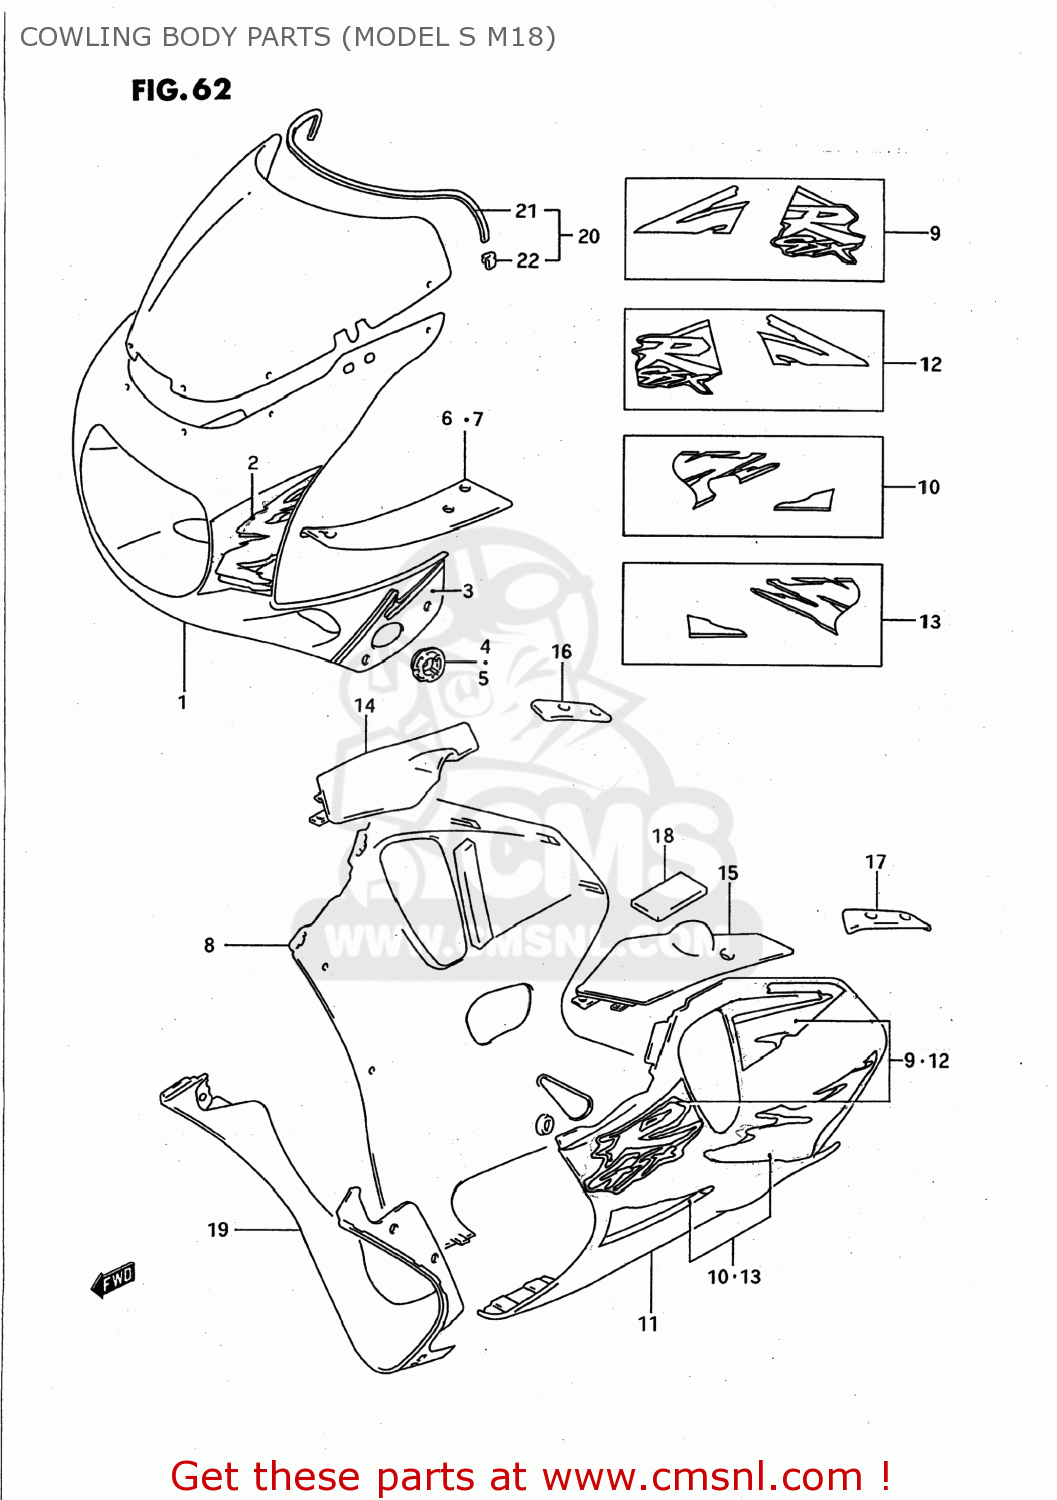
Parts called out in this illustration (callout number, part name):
1	COWLING ASSEMBLY,BODY
2	TAPE SET,COWL BODY FR
3	TAPE SET,COWLING BODY
4	PLATE,TURN SIGNAL,RIGHT
5	PLATE,TURN SIGNAL,LEFT
6	PANEL,COWLING,UPPER,RIGHT
7	PANEL,UPPER,LEFT
8	COWLING ASSEMBLY,UNDER,RIGHT
9	TAPE SET,COWLING,UNDER
10	TAPE SET,COWL UNDER LWR,R
11	COWLING ASSEMBLY,UNDER,LEFT
12	TAPE SET,COWL UNDER,L
13	TAPE,SAET COWL UNDER LWR,L
14	PANEL,LWR FR,R
15	PANEL,LWR FR,L
16	PANEL,LWR RR,R
17	PANEL,LWR RR,L
18	CUSHION,PANEL
19	COWLING,UNDER CTR
20	SCREEN SET,WINDOW
21	MOLDING WINDSCREEN
22	CLIP,WINDSCREEN MOLDING
